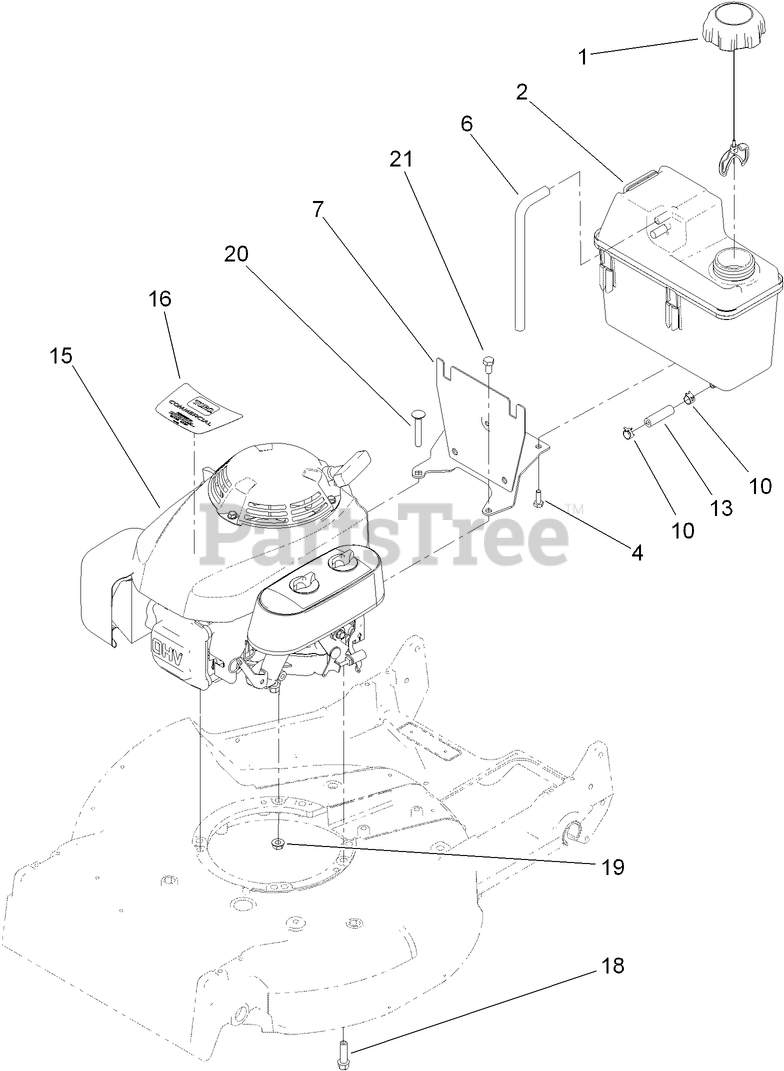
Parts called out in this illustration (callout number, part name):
2	TANK-FUEL
4	SCREW-HWH
6	HOSE-VENT, CANISTER
7	MOUNT-TANK
10	CLAMP-HOSE
13	HOSE-FUEL
18	SCREW-SHOULDER
19	BOLT-CARR
20	NUT-HF
21	SCREW-HH
